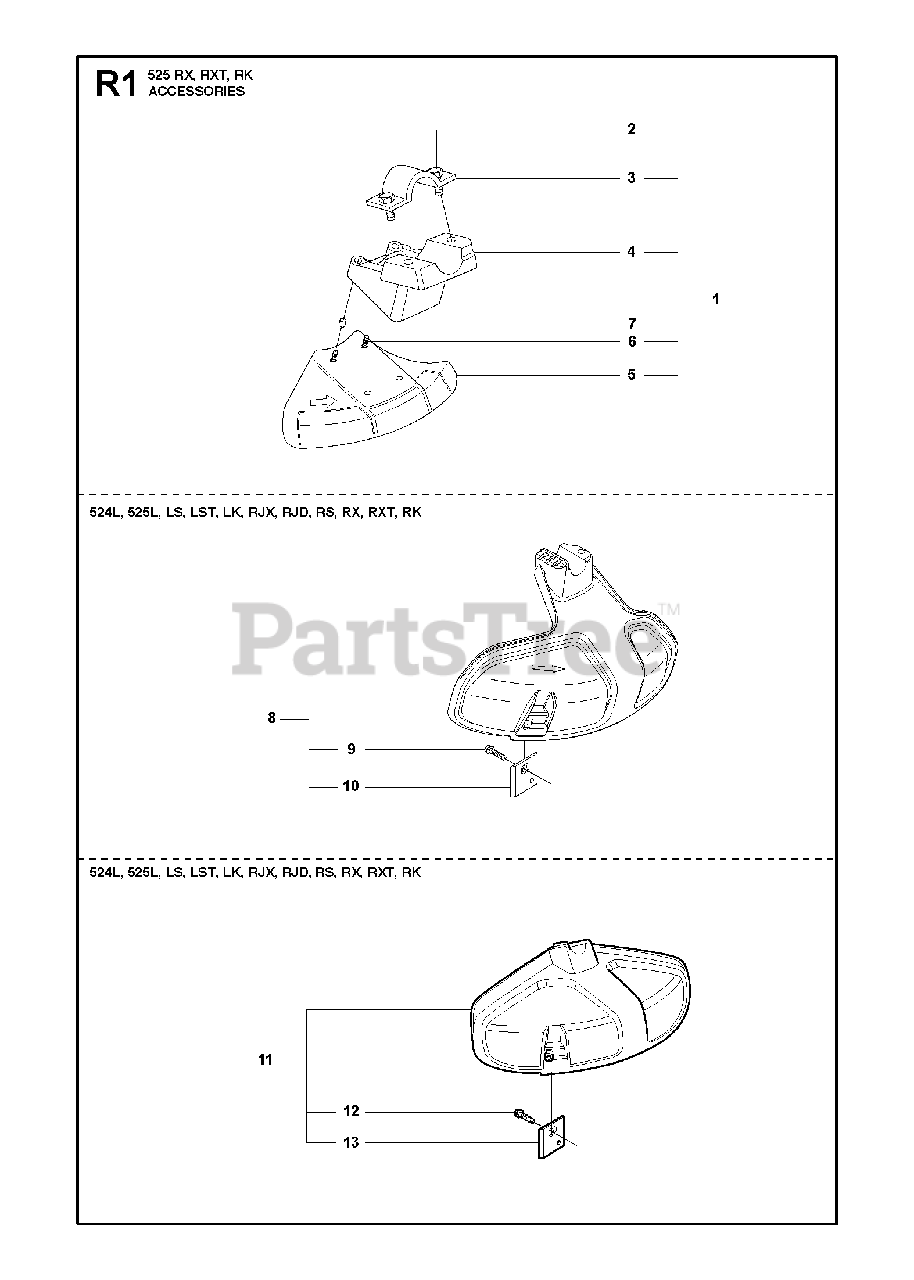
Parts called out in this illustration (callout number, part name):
1	TRIMMER GUARD ASSY
2	SCREW IHSCFMO
3	CLAMP
4	ADAPTER
5	METAL GUARD 200MM
6	SCREW
7	LOCKING NUT
8	TRIMMER GUARD ASSEMBLY
9	SCREW
10	LINE CUTTER
11	GRASS SHIELD
12	SCREW
13	LINE CUTTER
